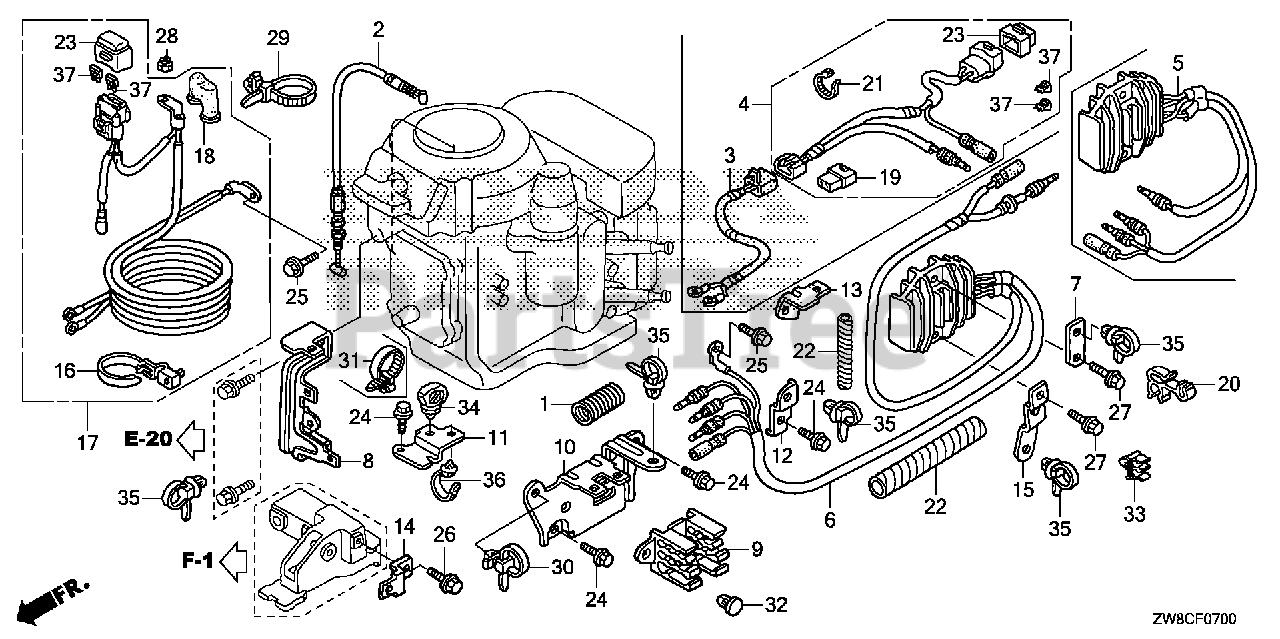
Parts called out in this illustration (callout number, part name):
1	TUBE, CORRUGATE (15MM)
2	CABLE, NEUTRAL STARTING
6	RECTIFIER ASSY., REGULATOR
7	BRACKET, CLIP F
8	BRACKET, CONNECTOR A
9	BRACKET, CONNECTOR (B)
10	BRACKET, CONNECTOR C
11	BRACKET, STARTER CABLE
12	BRACKET, CLIP B
13	BRACKET, FUSE CASE
15	BRACKET, E-CLIP
16	BAND, WIRE
16	BAND, WIRE (165MM) (BLACK)
17	CABLE ASSY., STARTER
18	COVER, MAGNETIC SWITCH TERMINAL
20	CLAMP, DISTRIBUTOR WIRE
22	TUBE, SPIRAL A
23	COVER ASSY., FUSE (20A)
24	BOLT, FLANGE (6X14) (CT200)
25	BOLT, FLANGE (6X12)
27	BOLT, FLANGE (6X26) (CT200)
28	NUT, LOCK (6MM)
29	BAND, WIRE (95MM)
30	STRAP, CABLE (118MM) (BLACK)
32	CLIP, ANCHOR
33	CLIP, FUEL TUBE
35	CLIP, HARNESS BAND (151.5MM) (NATURAL)
36	BAND, WIRE HARNESS (123.5MM) (BLUE)
37	FUSE, BLADE (20A)
